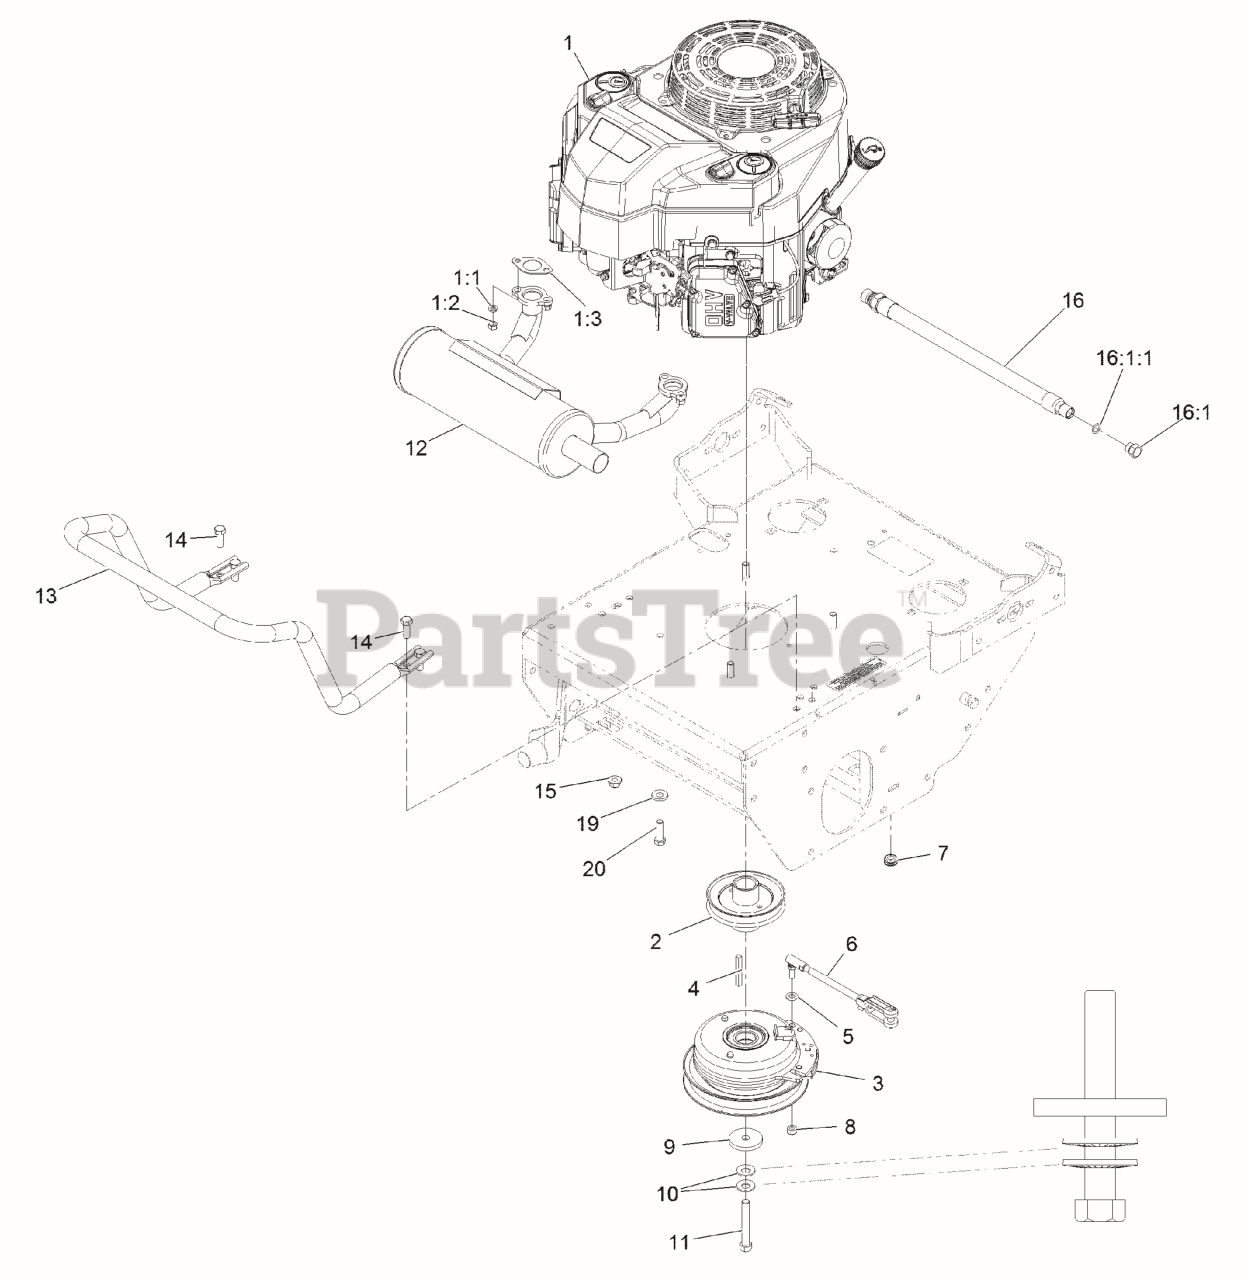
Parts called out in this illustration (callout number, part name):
1:1	WASHER-LOCK
1:3	GASKET-EXHAUST
2	SHEAVE, W/ HUB
3	CLUTCH, 105 FT/LBS, 1.13
4	KEY-SQUARE
5	WASHER-PLAIN
6	ASM, CLUTCH ANCHOR
7	GROMMET
8	NUT-LOCK
9	WASHER-CLUTCH
10	WASHER-SPRING
11	SCREW-HH
12	MUFFLER-HORIZONTAL
13	GUARD-MUFFLER
14	SCREW-HH
15	NUT-HF, NI
16	ASM, ENGINE OIL DRAIN HOS
16:1	PLUG-HH
16:1:1	O-RING
19	WASHER-BELLEVILLE
20	SCREW-HH
